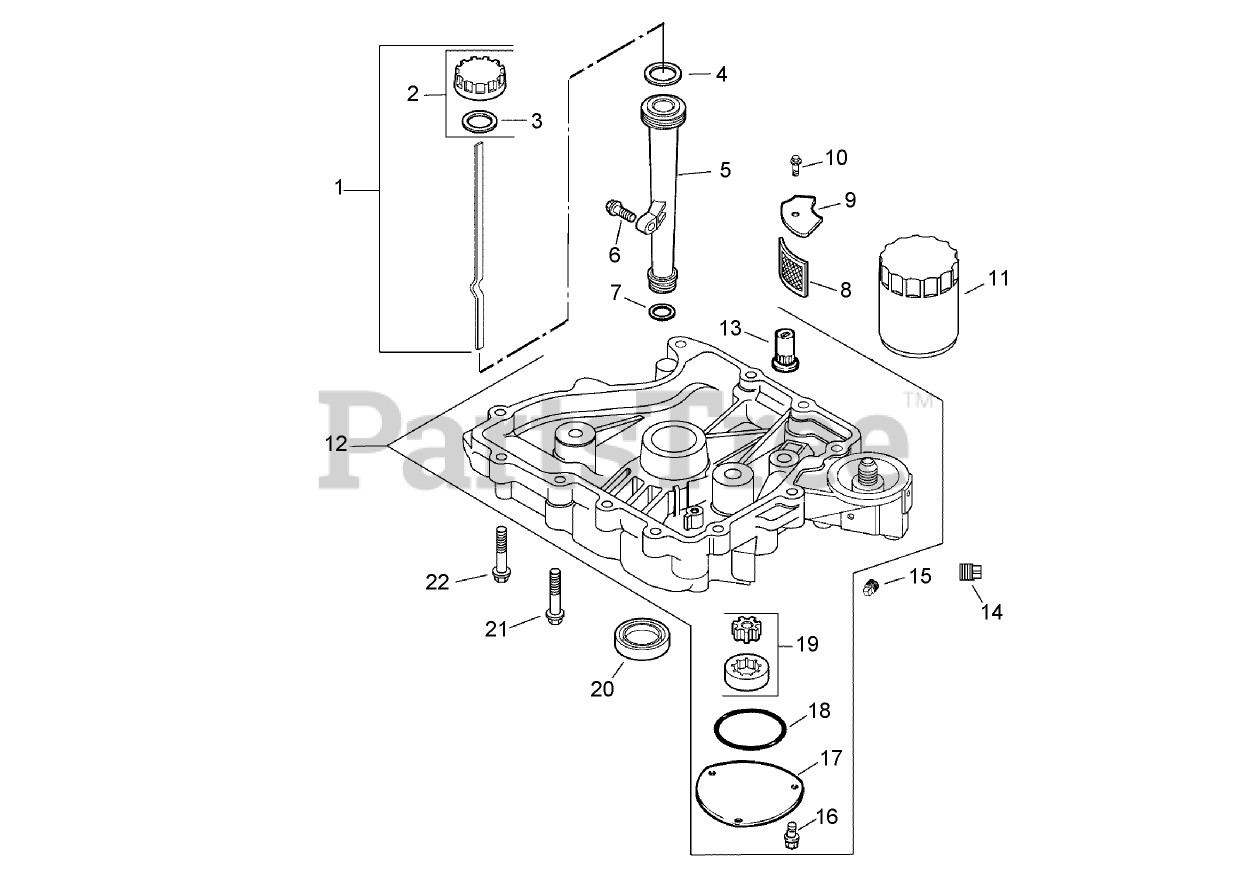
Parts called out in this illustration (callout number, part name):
1	Dipstick ASM (Incl. Ref. #2 and 3)
2	Oil Fill Cap ASM (Incl. Ref. #3)
3	O-Ring (Dipstick)
4	O-Ring (Upper Oil Fill Tube)
5	OIL FILL TUBE KIT
6	SCREW-FLANGE, THREAD FORMING (M5X.8X20)
7	O-Ring (Lower Oil Fill Tube)
8	Screen-Pickup, Oil
9	Cover-Screen, Oil Pickup
10	SCREW-FLANGE, THREAD FORMING (M5X0.8X16)
11	FILTER-OIL
12	Oil Pan ASM (Incl. Ref. #13, 16-19)
13	Valve-Relief, Oil Pressure
14	PLUG-PIPE, SQ HD (3/8)
15	Plug-Pipe (1/8in)
16	SCREW-FLANGE, THREAD FORMING (M5X0.8X16)
17	Cover-Pump, Oil
18	O-Ring (Oil Pump Cover)
19	Oil Pump ASM
20	Seal-Oil (PTO end)
21	Screw-HF (M8x1.25x45)
22	SCREW-FLANGE (M8X1.25X45)
